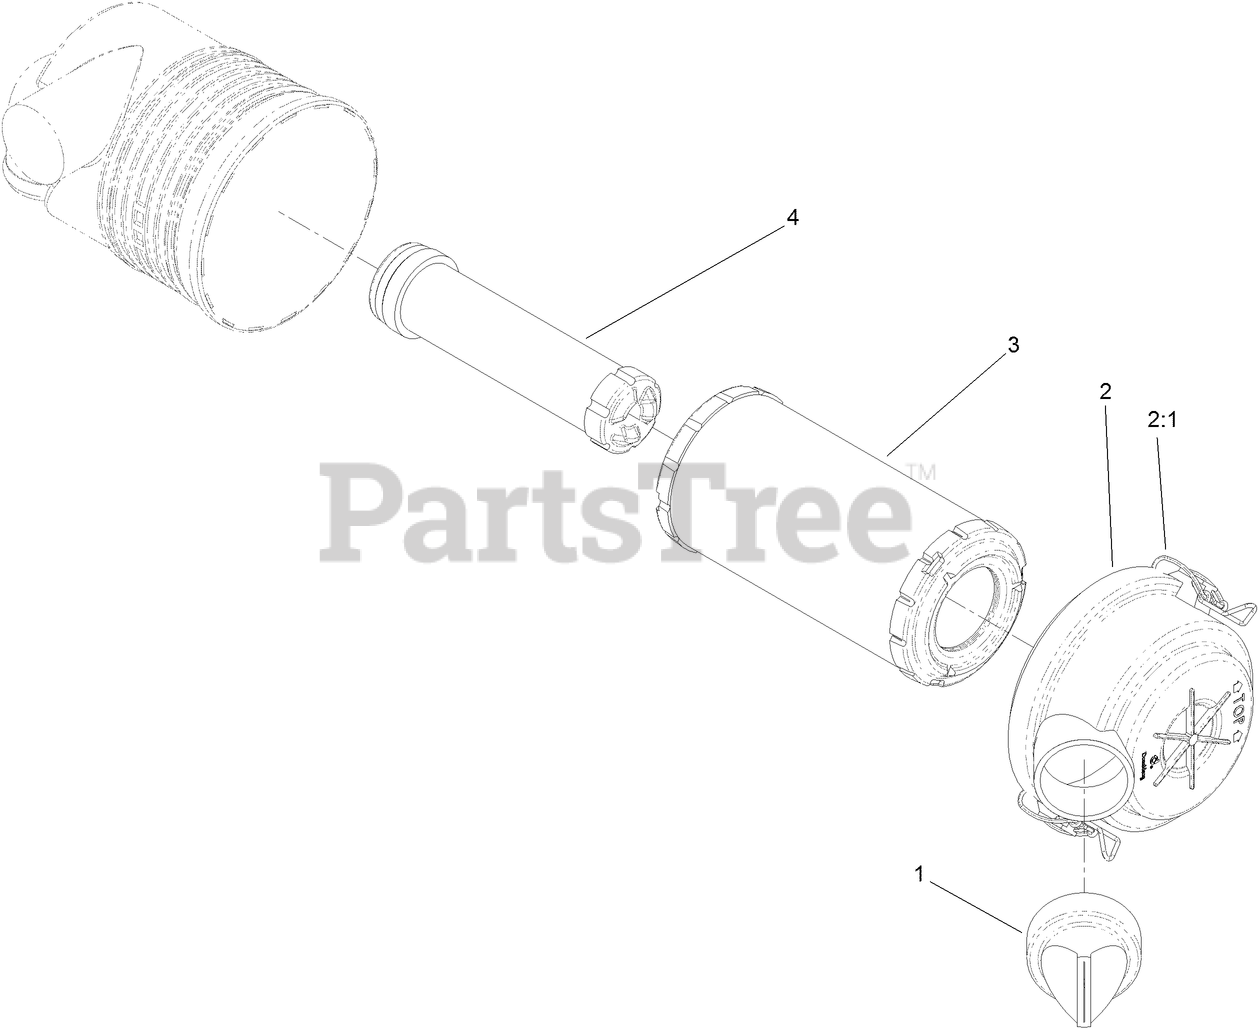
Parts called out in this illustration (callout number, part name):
1	VALVE-VACUATOR
2	COVER ASM
2:1	LATCH-CLEANER, AIR
3	FILTER-AIR
4	FILTER-ELEMENT, SAFETY
